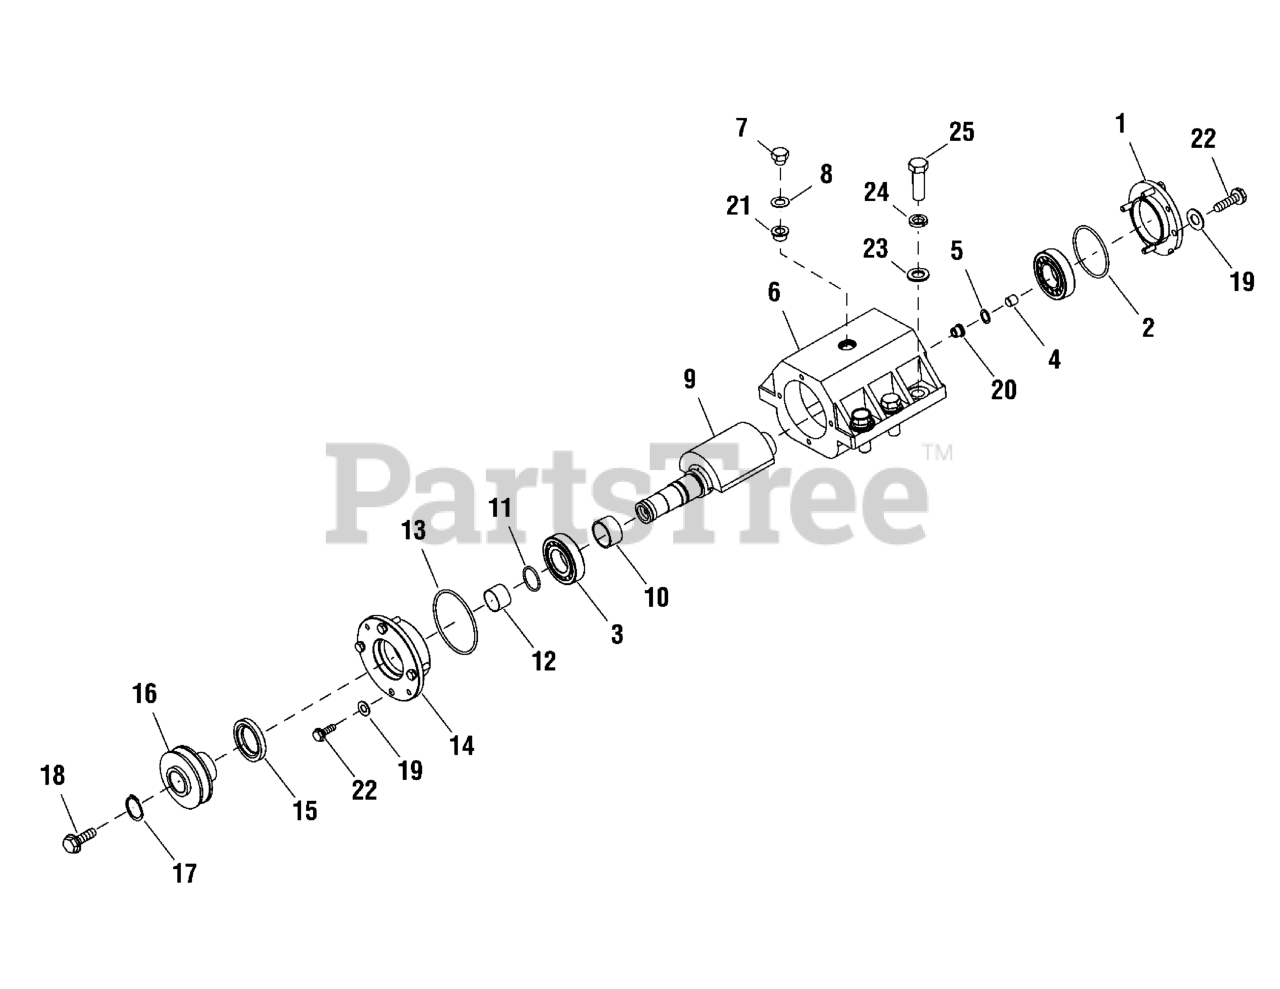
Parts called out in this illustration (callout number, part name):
1	COVER, Eccentric Box
2	O-RING
3	BEARING, Single Row Roller
4	PLUG, Hex Socket Head, M10
5	GASKET
6	ECCENTRIC BOX
7	PLUG, Hex Head, M14
8	GASKET
9	ECCENTRIC SHAFT
10	BUSHING
11	O-RING
12	BUSHING
13	O-RING
14	COVER, Eccentric Box
15	LIP OIL SEAL RING
16	PULLEY, Eccentric Box
17	CIRCLIP
18	BOLT, Venting
19	WASHER, Spring
20	THREAD BUSHING A
21	THREAD BUSHING B
22	BOLT, Hex, 18 x 30
23	WASHER, Flat
24	WASHER, Spring
25	BOLT, Hex, M16 x 50
